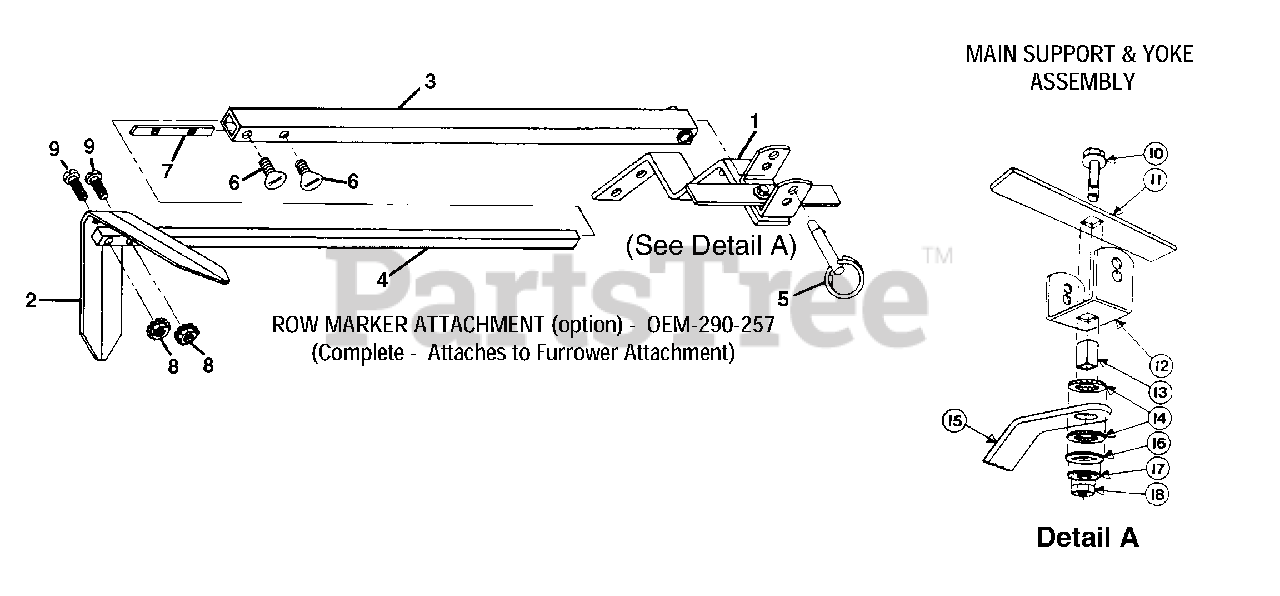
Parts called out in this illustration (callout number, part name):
1	Main Support & Yoke Assy-complete.
2	Marker Blade-blade only
3	Marker Arm - main arm
4	Marker Arm - extension arm with stop pin
5	Hitch Pin
6	Thumbscrew-1/4-20 x 1/2
7	Nut Bar
8	Nut-hex, 10-24 w/attached start washers
9	Screw-round hd., 10-24 x 1
10	Screw-hex flanged locking, 3/8-16 x 1-1/2
11	Stop Bar
13	Tube Key-square
14	Washer-friction
15	Main Support
16	Washer-square hole
17	Washer-disc spring
18	Nut-hex 3/8-16
